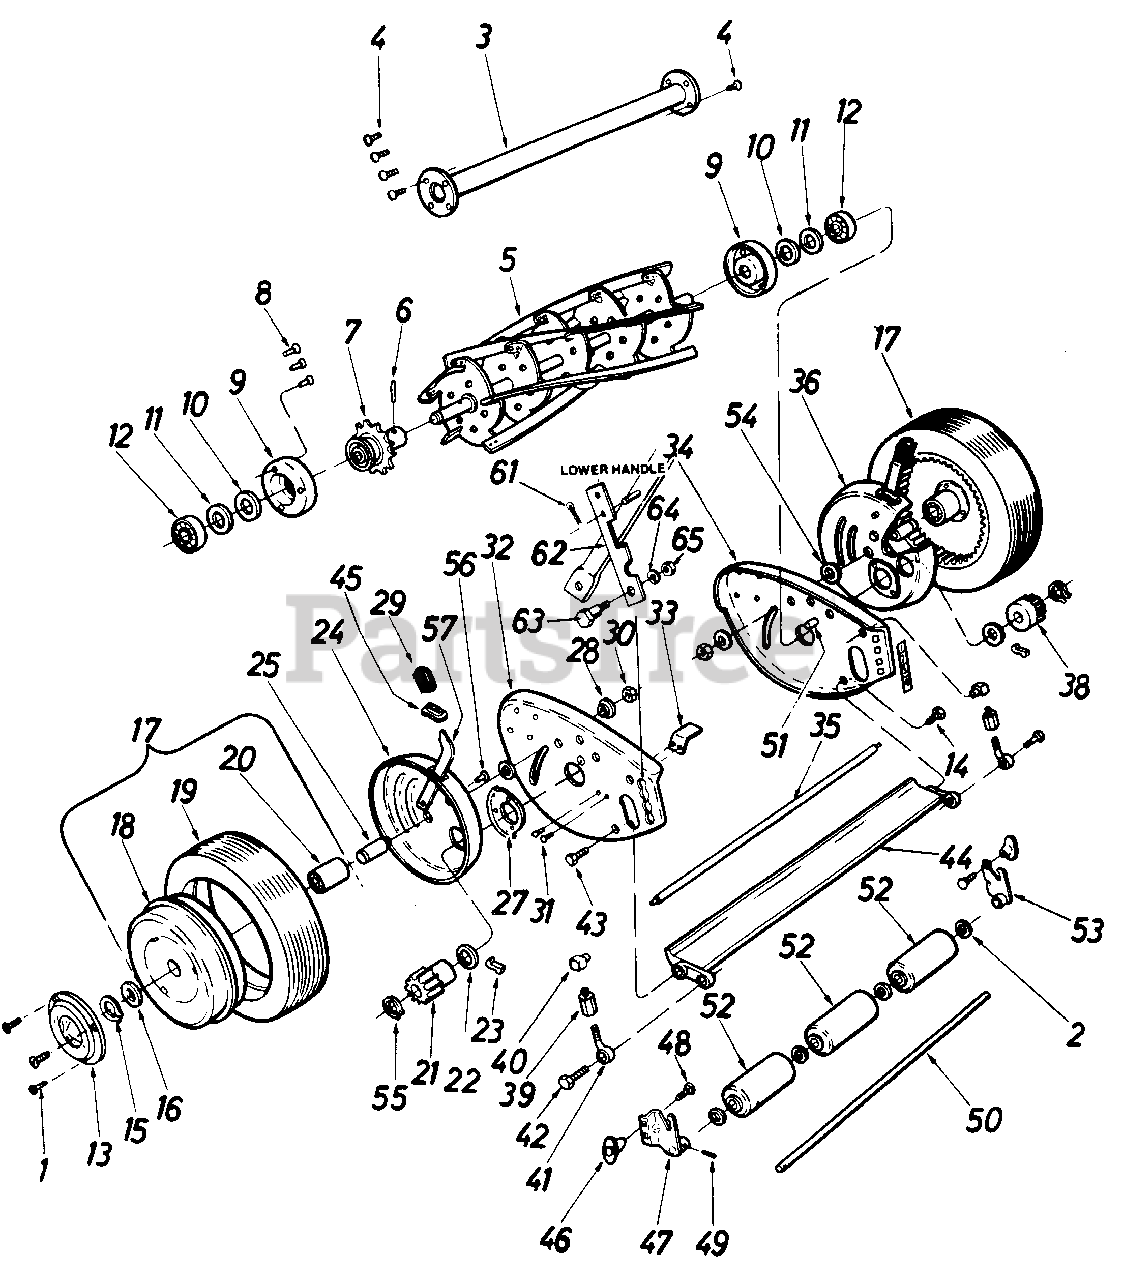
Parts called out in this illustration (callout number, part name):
1	Ph. Hd. Scr. #10-32 x .62" Lg.
2	Roller Washer
3	21" SpacerTubeAss'y.
4	Rivet-3/16 x 3/8"
5	21n Reel Ass'y.
6	Roll Pin
7	Sprocket Anti-Wind Cup, and Hub Ass'y.
8	Rivet 3/16 x 13/32
9	Retainer
10	Felt Washer
11	Felt Retainer
12	Bearing
13	Hub Cap
14	Scr.Cuter Bar L.H. Thd.
15	Retaining Ring
16	Washer
17	Wheel Ass'y.Comp.
18	Wheel Ass'y. w/Bearing
19	Tire 10.25 x 2.50
20	Bearing
21	Pinion Gear-R.H.
22	Felt Washer
24	Gear Housing-L.H.
27	Retainer
28	Bushing
29	Wheel Adj. Knob
30	Hex Lock Nut
31	Hex Sems Scr. 10-32 x .375" Lg.
32	End Plate w/Trunnions
33	Scraper
34	End Plate w/Trunnions
35	End Plate Spacer
36	Gear Housing
38	Pinion Gear
39	Turnbuckle Nut
40	Trunnion
42	Screw
43	Scr.Cuter Bar-R.H. Thd.
44	21" Cutter Bar Ass'y.
45	Dust Cover
46	Roller Adj. Knob
47	Roller Brkt. Ass'y.L.H.
48	Hex Scr. 5/16-18 x .62" Lg.
49	Roll Pin
50	Roller Shaft
51	Trunnion
52	Roller
53	Roller Brkt. Ass'y.R.H.
54	Washer
55	Retaining Ring
56	Hex Scr. #10-32 x .375" Lg.
57	Spring and Trunnion Ass'y.
61	Internal Coter Pin
62	Handle Brace
63	Shld. Bolt 5/16-18 Thd.
64	L-Wash. 5/16" Scr.
65	Hex Nut 5/16-18 Thd.
